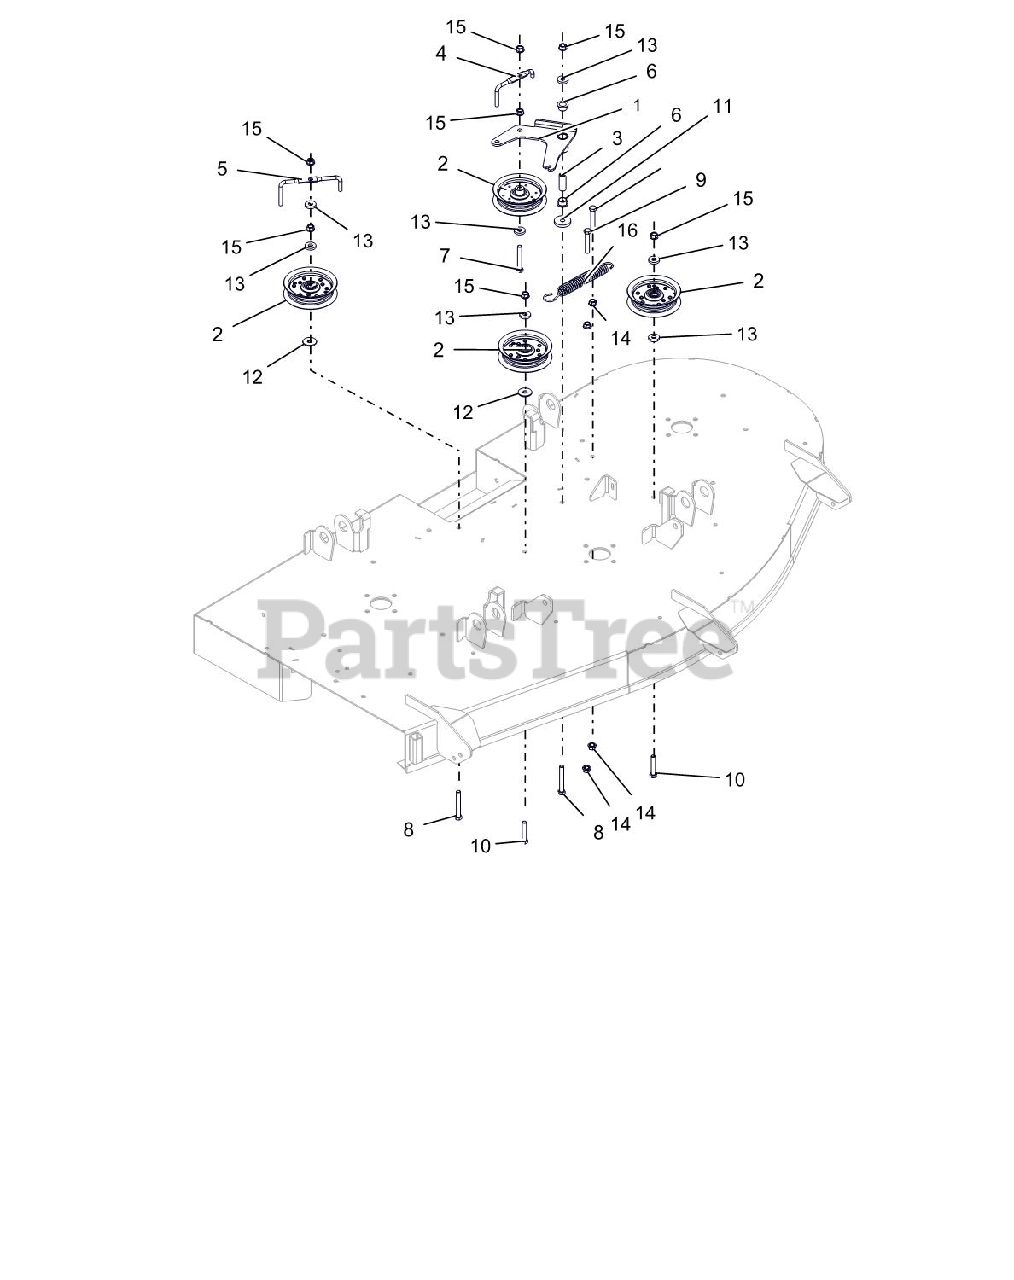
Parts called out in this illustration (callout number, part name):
1	WLDMT, IDLER ARM-42"
2	ASM, IDLER 4"
3	SPACER, .375IDX.625ODX1.66 PM
4	WIREFORM, BELT FINGER
5	BELT FINGER
6	BSHG-FLG, .625X.750X.500X1.00
7	@BLT-HEX .38-16X2.50 GR5 YWZC
8	@BLT-HEX .38-16X2.75 GR5 YWZC
9	@BLT-HEX .38-16X2.25 GR5 YWZC
10	@BLT-HEX .38-16X2.00 GR5 YWZC
11	WSHR,FLT STL.406X1.50X.245YWZC
12	@WSHR-FL-STL .406X1.25X.10 ZC
13	WSHR-FL-STL .406X1.00X.188 YWZ
14	@NUT-SPNLK-FLG .375-16 YWZC
15	@NUT-LK-TOP-FLG .38-16 YWZC
16	SG-TENS .135X.98X6.0 WLD 62
